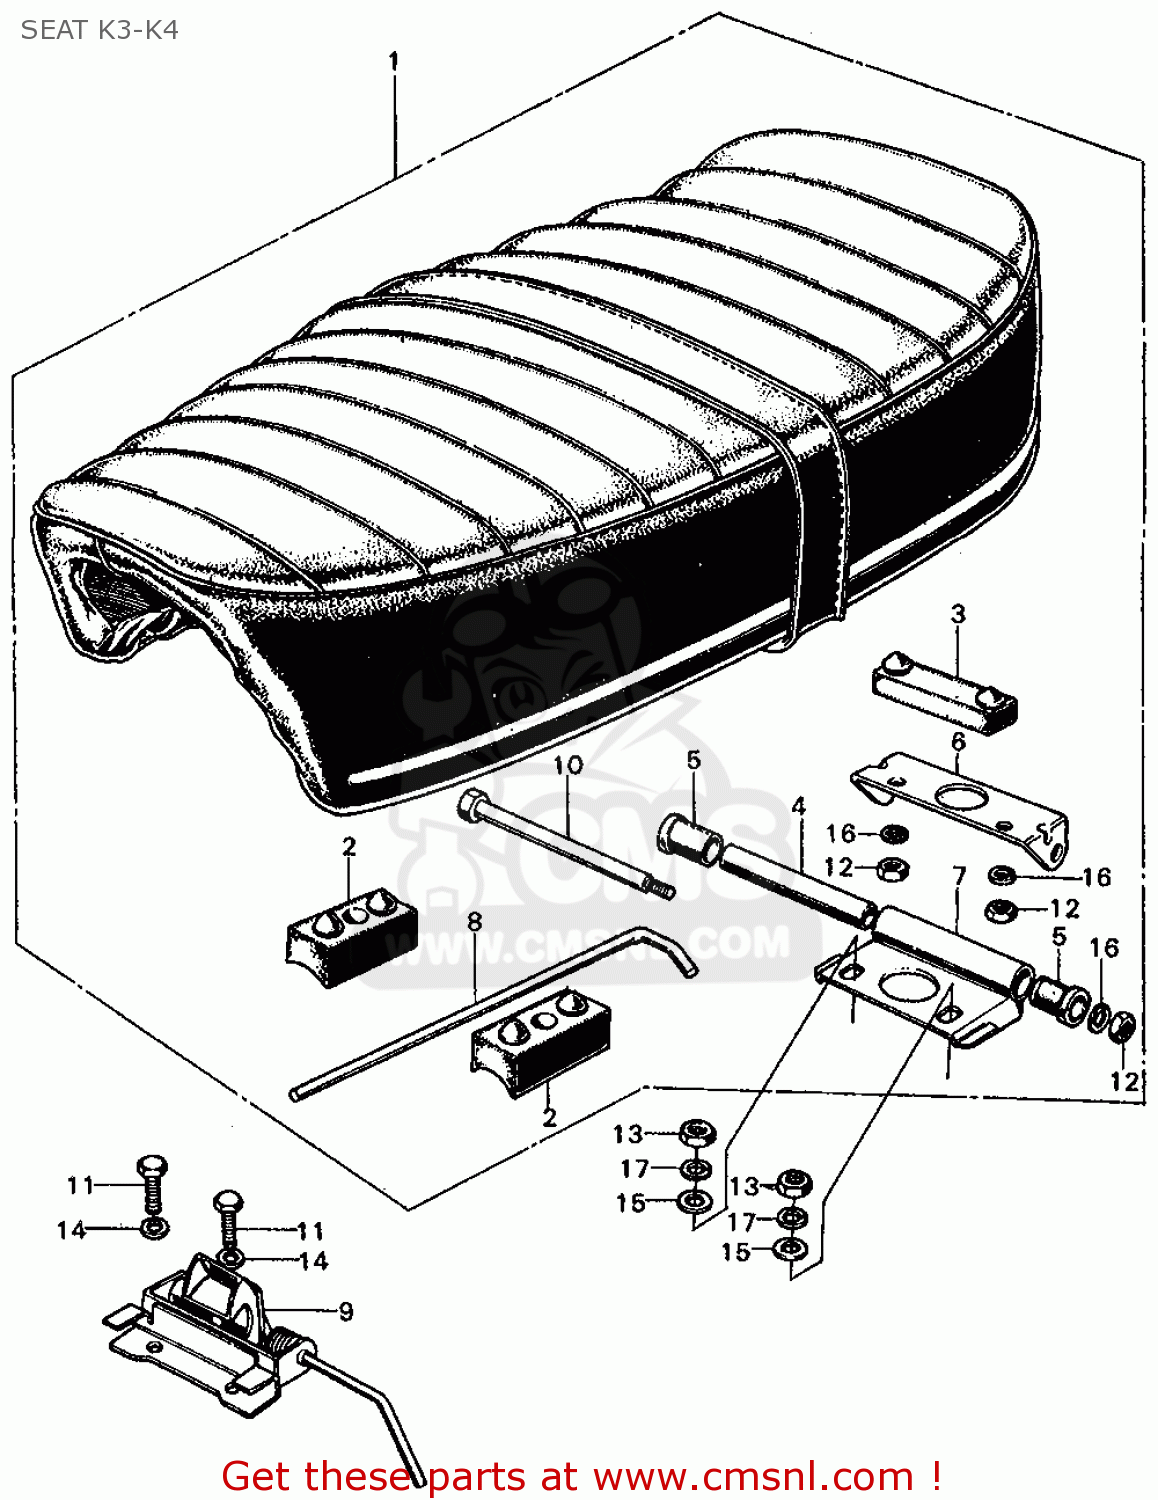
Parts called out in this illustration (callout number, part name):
1	SEAT,DOUBLE
2	RUBBER,SEAT SETT.
3	RUBBER B SEAT
4	COLLAR,SET HINGE
5	RUBBER,SEAT HINGE
6	PLATE,SEAT HINGE
7	BRACKET,SEAT
8	BAR,SEAT STOPPER
9	CATCH ASSY,SEAT
10	BOLT,SEAT HING
11	BOLT,HEX 6X12
12	NUT HEX 6MM
14	WASHER PLAIN 6MM
15	WASHER,PLAIN,8MM
16	WASHER,SPRING,6MM
17	SPG-WASHER 8MM
